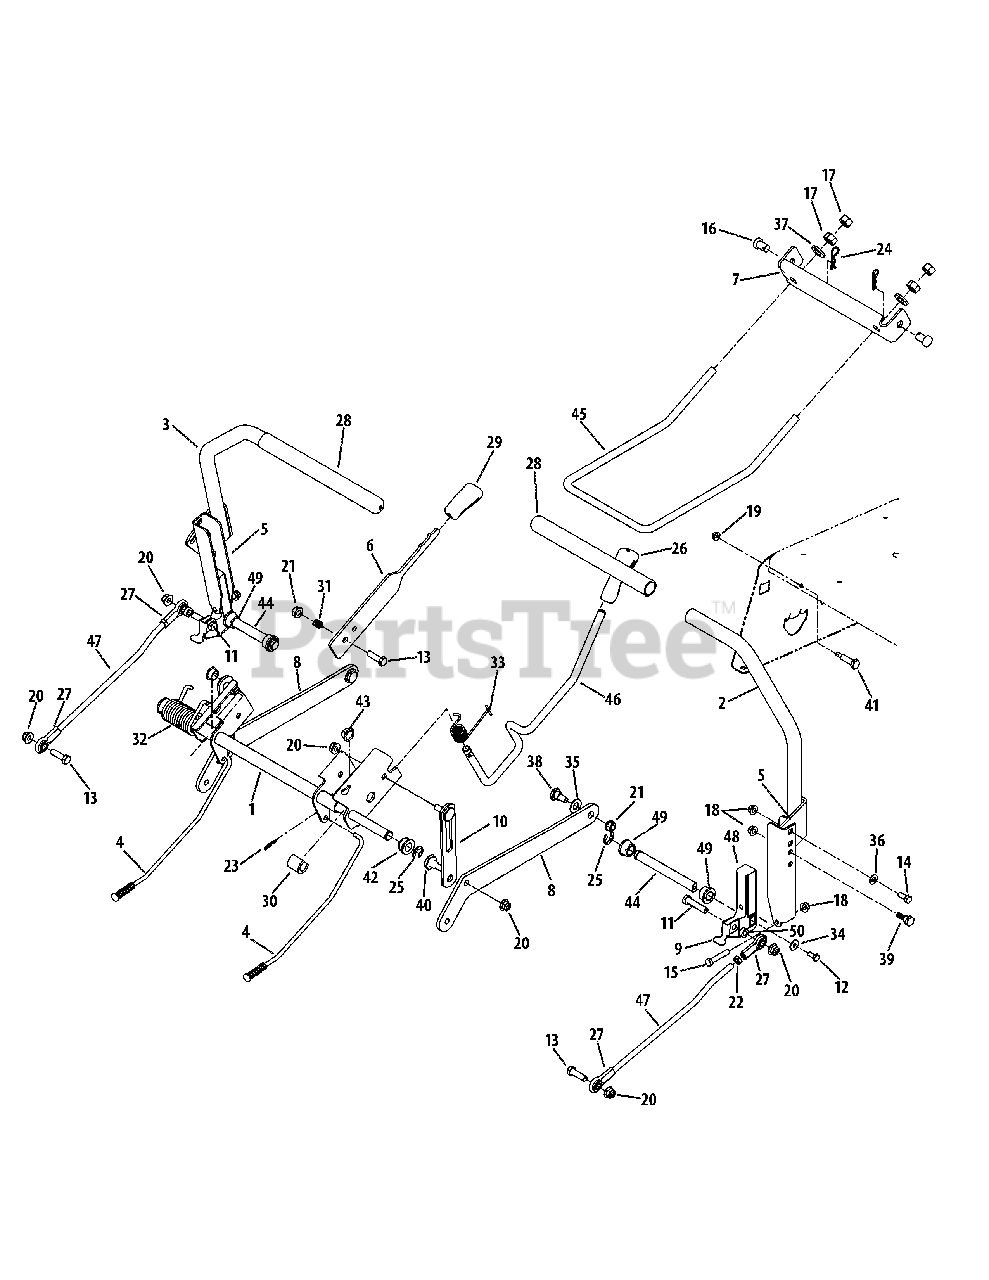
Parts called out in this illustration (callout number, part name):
1	Deck Lift Shift Assembly
2	RH Lapbar Lever Assembly
3	LH Lapbar Lever Assembly
4	Brake Rod Assembly
5	Lapbar Pivot Bracket
7	Front Deck Hanger Bracket
8	Deck Lift Arm Plate
9	Switch Actuator Bracket
10	Lift Link Plate
11	Hex Screw, 3/8-16 x 1.75
12	Hex Screw, 1/4-20 x .625
13	Hex Screw, 3/8-16 x 1.25
14	Hex Screw, 5/16-18 x .75
15	Hex Screw, 5/16-18 x 1.75
16	Clevis Pin, .50 x .78
17	Hex Nut, 1/2-13
18	Flange Lock Nut, 5/16-18
19	Flange Lock Nut, 1/4-20
20	Flange Lock Nut, 3/8-16
21	Flange Lock Nut, 3/8-16
22	Jam Nut, 3/8-24
23	Bow-Tie Cotter Pin
24	Cotter Pin, .080 x 1.5625
26	Handle Grip
28	Lapbar Grip
29	Selector Handle
30	Spacer, .621 x 1.00
31	Compression Spring, .50 x .50
32	Torsion Spring, 1.19 x 2.78
33	Spring, Torsion RZT
34	Bell Washer, .265 x .75 x .062
35	Flat Washer, .510 x 1.00 x .060
36	Flat Washer, .344 x .688 x .065
37	Flat Washer, .531 x 1.062 x .134
38	Shoulder Bolt, 3/8-16 x .496 x .336
39	Shoulder Screw, 5/16-18 x .437 x .268
40	Shoulder Screw, .500 x .434
41	Shoulder Screw, .374 x 1.16
42	Hex Flange Bearing
43	Flange Bearing, .626 x .938 x .344
44	Shaft Control
45	Front Hanger Deck Lift Rod
46	Deck Lift Handle Rod
47	Lapbar Rod Control
48	Control Hub
49	Hex Flange Bearing
50	Spacer, .380 x .625 x .265
